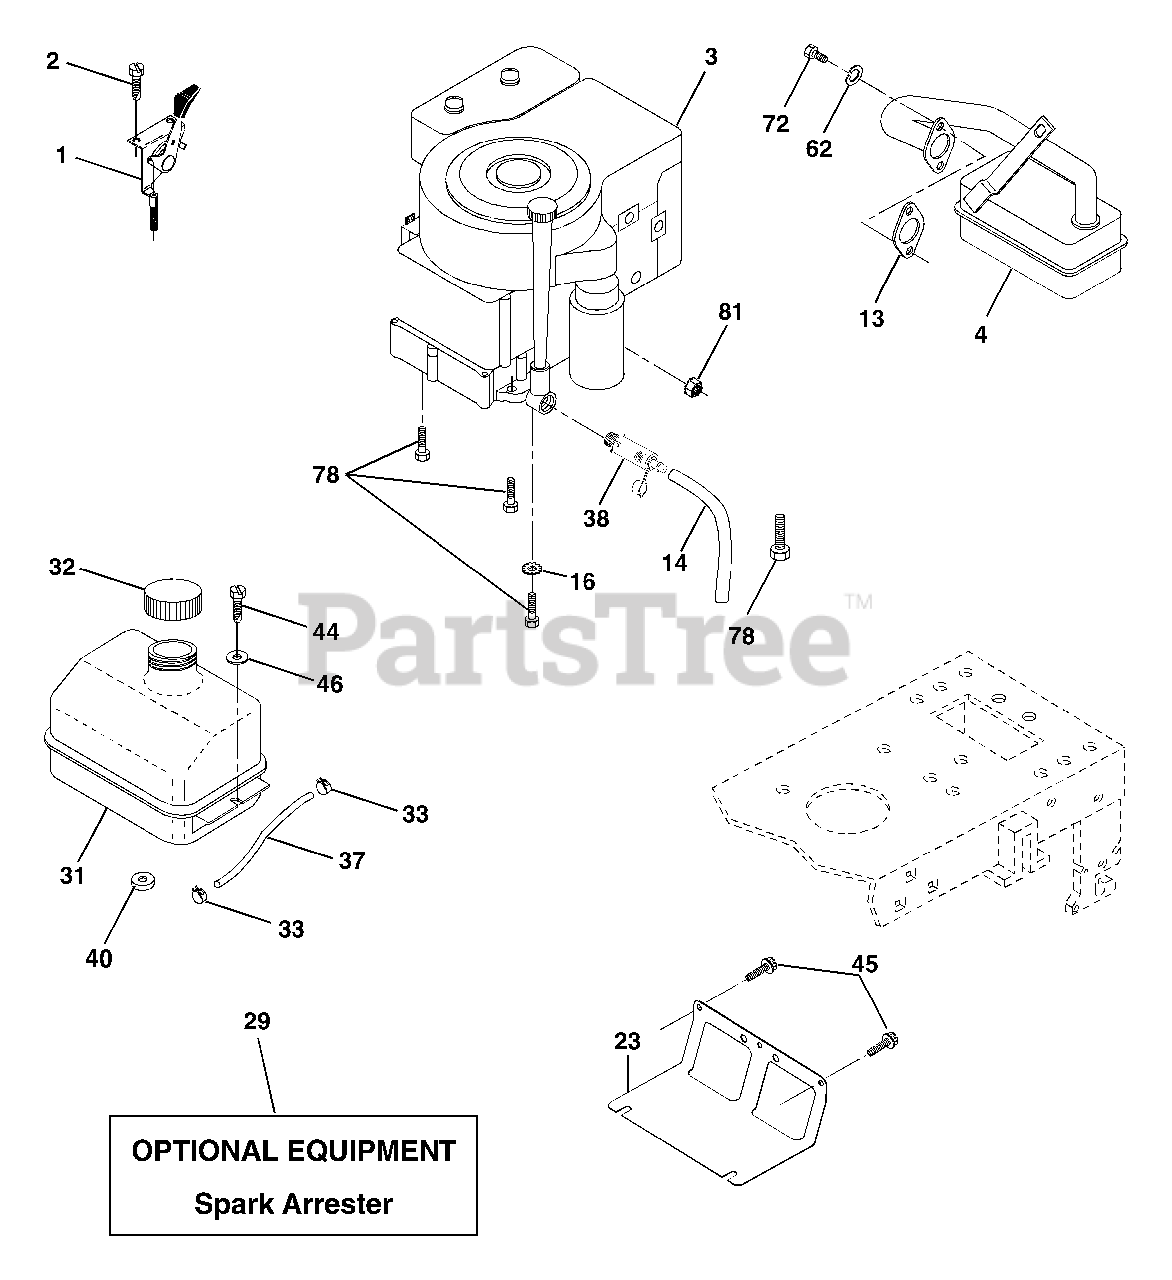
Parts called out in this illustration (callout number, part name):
1	Control Throt /Ch 23.5 Lh Flag
2	Screw Hex Thd Cut 1/4-20x5/8 T
4	Muffler Exhaust B&S Lt
13	Gasket 1 313 Id Tin Plated
14	Tube Drain Oil Easy
16	Washer Lock Ext Tooth 3/8
23	Shield Browning/Debris Guard
29	Arrestor Spark
31	Tank Fuel 1 25 Fr
32	Cap Asm Fuel W/sym Vented
33	Clamp Hose Blk
37	Line Fuel 20"
38	Plug Oil Drain
40	Bushing Snap Nyl Blk Fuel Line
44	Screw Hexwsh Thdrol 1/4-20x3/4
45	Screw Hex Wsh Thdrol 3/8-16
46	Washer 9/32 X 7/8 X 16ga
62	Washer Lock Hvy Hlcl Spr 5/16
72	Screw Hexhd Cap 5/16-18x3/4
78	Screw Thdrol 3/8-16x1-1/4
81	Nut Keps Hex 1/4-20 Unc
